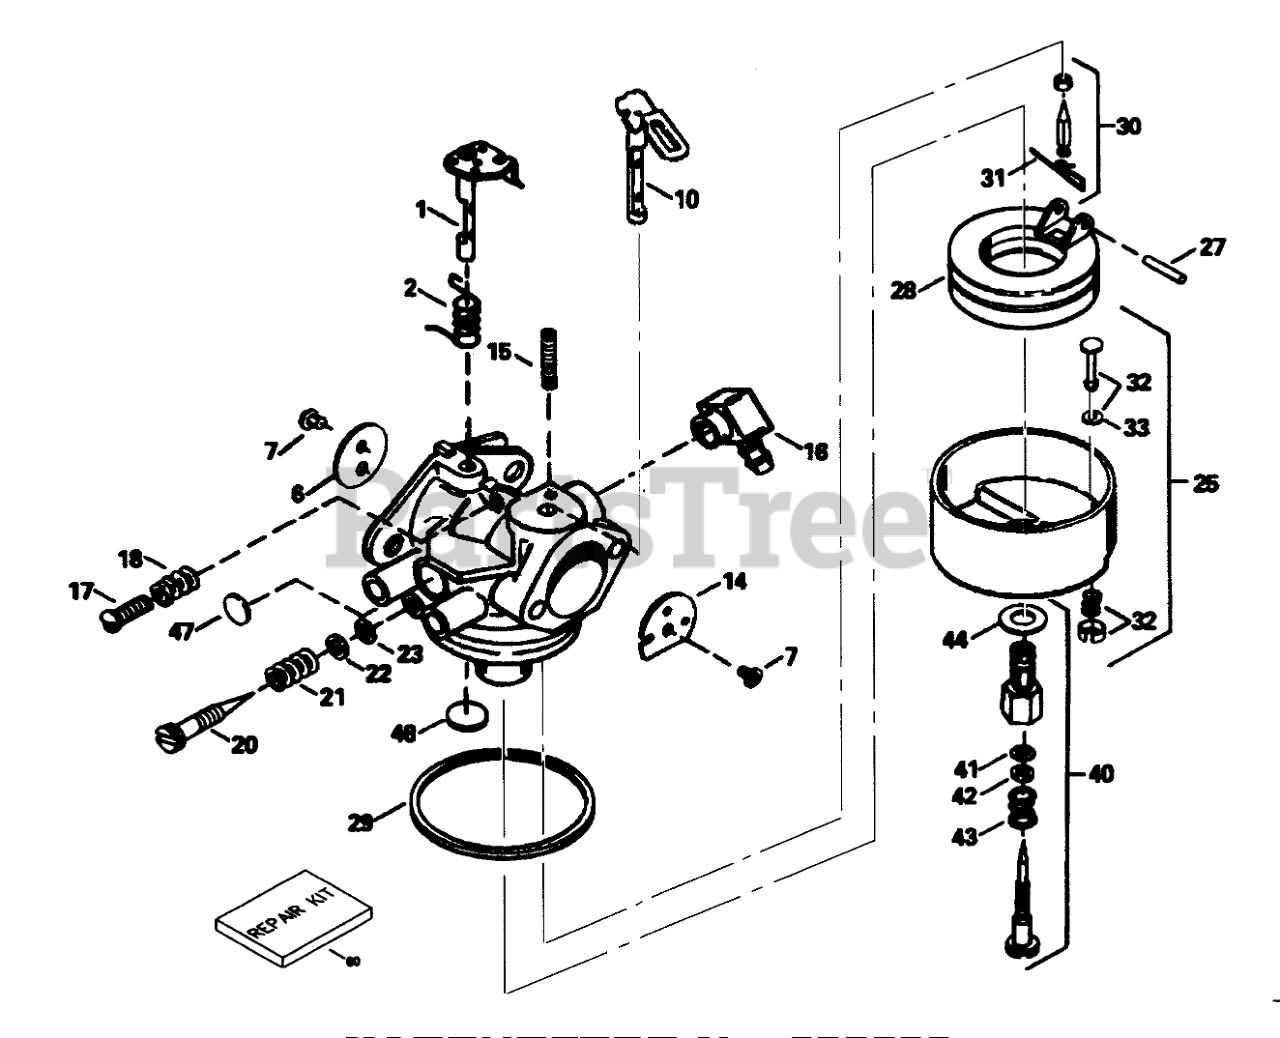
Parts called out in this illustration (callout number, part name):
1	Throttle-Shaft & Lever Asm
2	Spring-Return, Throttle
6	Shutter-Throttle
7	Screw-Shutter
10	Choke Shaft & Lever ASM
14	Choke Shutter
15	Spring-Positioning, Choke
16	Fitting-Fuel
17	Screw-Throttle Crack Screw / Idle Speed
18	Spring-Tension
20	Screw-Idle Mix
21	Spring-Tension
23	"O"Ring
25	Float-Asm (Incl. Ref. # 32 & 33)
27	Shaft-Float
28	Float
29	O Ring-Bowl, Float
30	Needle, Seat & Clip (Incl. Ref.# 31)
31	Clip-Spring
32	Bowl Drain ASM
33	Gasket-Plunger, Drain
40	Main-Adjusting Screw (Incl. Ref. #41-44)
41	"O"Ring
44	Washer-Bowl Nut
47	Plug-Welch, Idle Mixture Well
48	Plug-Welch, Atmospheric Vent
60	Kit-Repair
